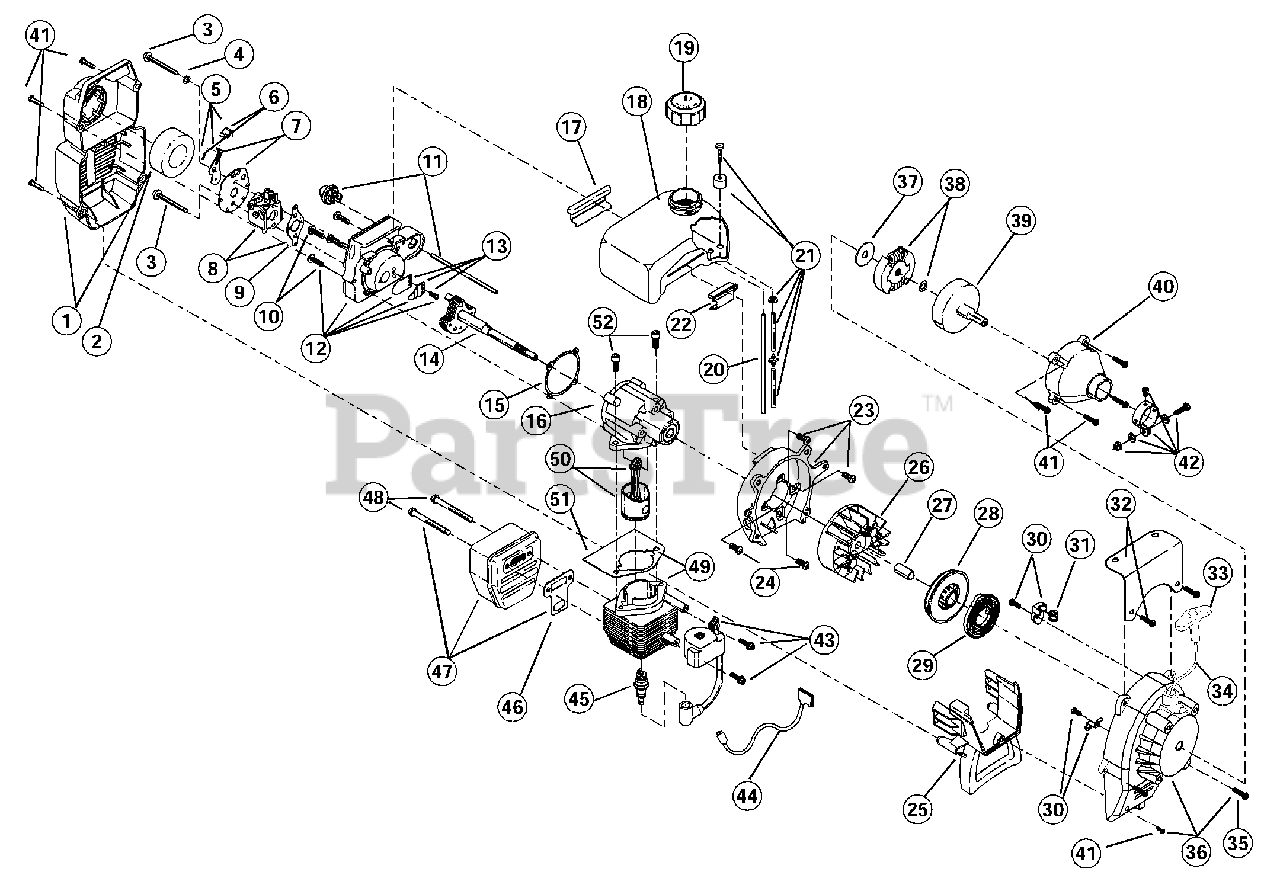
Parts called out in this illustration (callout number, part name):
1	Air Cleaner/Muffler Cover Assembly
2	Air Cleaner Filter
3	Carburetor Mounting Screw Assembly
4	Wavey Washer
5	Choke Lever Assembly
6	Choke Knob and Screw
7	Choke Lever and Plate
8	Carburetor Assembly
9	Carburetor Gasket
10	Carb Mount Screw
11	Primer and Hose Assembly
12	Carb Mount Assembly
13	Reed Assembly
14	Power Shaft Assembly
15	Carburetor Mount Gasket
16	Crank Case Service Assembly
17	Rear Mounting Pad
18	Fuel Tank Assembly
19	Fuel Cap Assembly
20	Fuel Return Line
21	Fuel Line Assembly
22	Front Mounting Pad
23	Shroud Assembly
24	Shroud Screw
25	Shroud Extension and Stand
26	Flywheel Assembly
28	Recoil Pulley Assembly
29	Recoil Spring
30	Pulley Retainer Assembly
31	Rope Guide
32	Fuel Tank Guard Assembly
33	Pull Handle
35	Housing Screw
36	Starter Housing Assembly
37	Clutch Washer
38	Clutch Rotor Assembly
39	Clutch Drum Assembly
40	Clutch Cover Assembly
41	Clutch Cover Screw
42	Upper Clamp Assembly
43	Module Assembly
44	Wire Lead
45	Spark Plug
46	Exhaust Gasket
47	Muffler Assembly
48	Muffler Mounting Bolt Assembly
49	Cylinder Assembly
50	Piston and Rod Assembly
51	Cylinder Gasket
52	Cylinder Bolt
